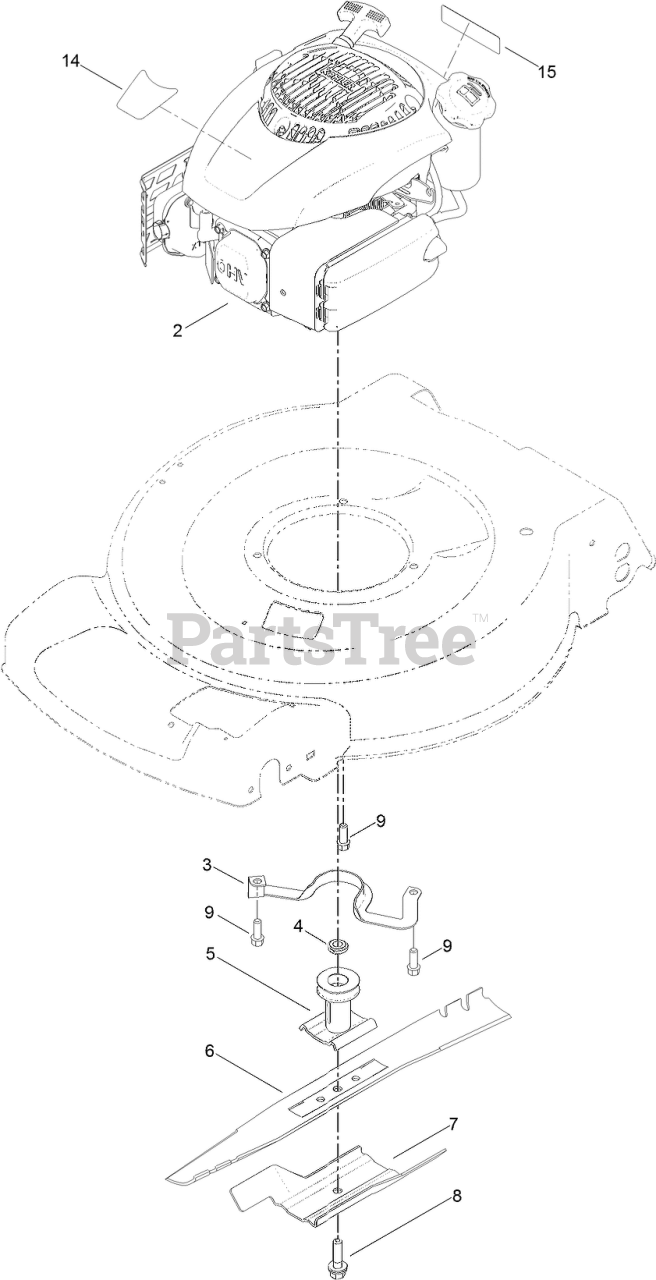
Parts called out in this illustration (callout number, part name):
3	Guide-Belt
4	Spacer-Driver
5	DRIVER-BLADE
6	BLADE-22IN
7	SUPPORT-BLADE
8	BOLT-BLADE
9	SCREW-TAPTITE
14	DECAL-SHROUD
15	DECAL-ARRESTER, SPARK
